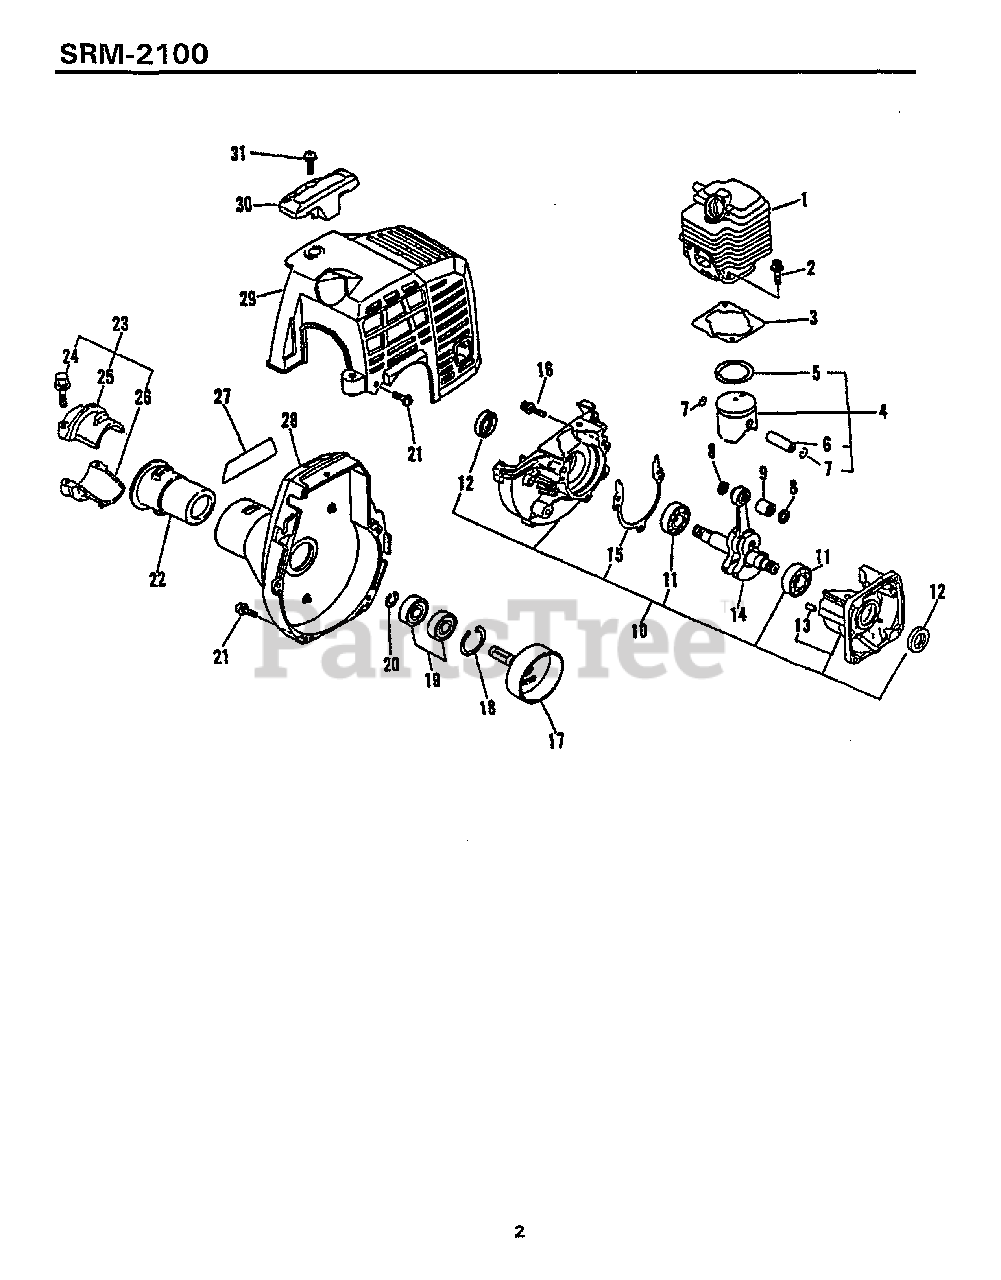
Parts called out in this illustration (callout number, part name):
1	CYLINDER
2	BOLT 5×22
3	GASKET, CYLINDER
4	PISTON KIT
5	RING, PISTON
6	PIN, PISTON 8
7	RING, SNAP
8	WASHER, THRUST
9	BEARING, NEEDLE
10	CRANKCASE KIT
11	BEARING, BALL 6201
12	SEAL, OIL 12
13	PIN, LOCATING 4×8
14	CRANKSHAFT ASSY
15	GASKET, CRANKCASE
16	BOLT 5×28
17	DRUM, CLUTCH
18	RING, SNAP 28
19	BEARING, BALL 6001
20	RING, RETAINING - 12
21	BOLT 4×16
23	HOLDER KIT
24	BOLT - 5×25
27	LABEL - MODEL SRM-2100
28	FAN CASE ASSY
29	COVER, ENGINE
30	GUARD, TOP
31	SCREW 5×16
